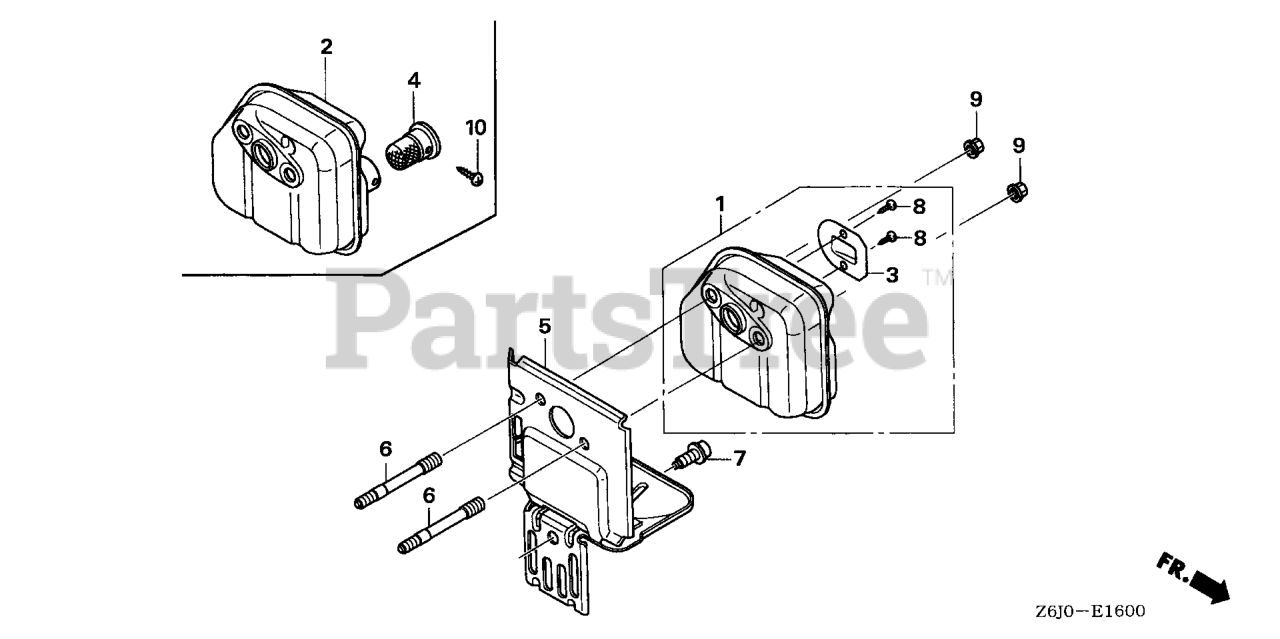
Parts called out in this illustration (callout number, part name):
1	MUFFLER
3	ARRESTER, SPARK
5	GUIDE, AIR EX.
6	BOLT, STUD (5X52)
7	BOLT, SOCKET (5X10)
8	SCREW, TAPPING (4X6) (TO INSTALL OPTIONAL SPARK ARRESTER)
9	NUT, SELF-LOCK (5MM)
